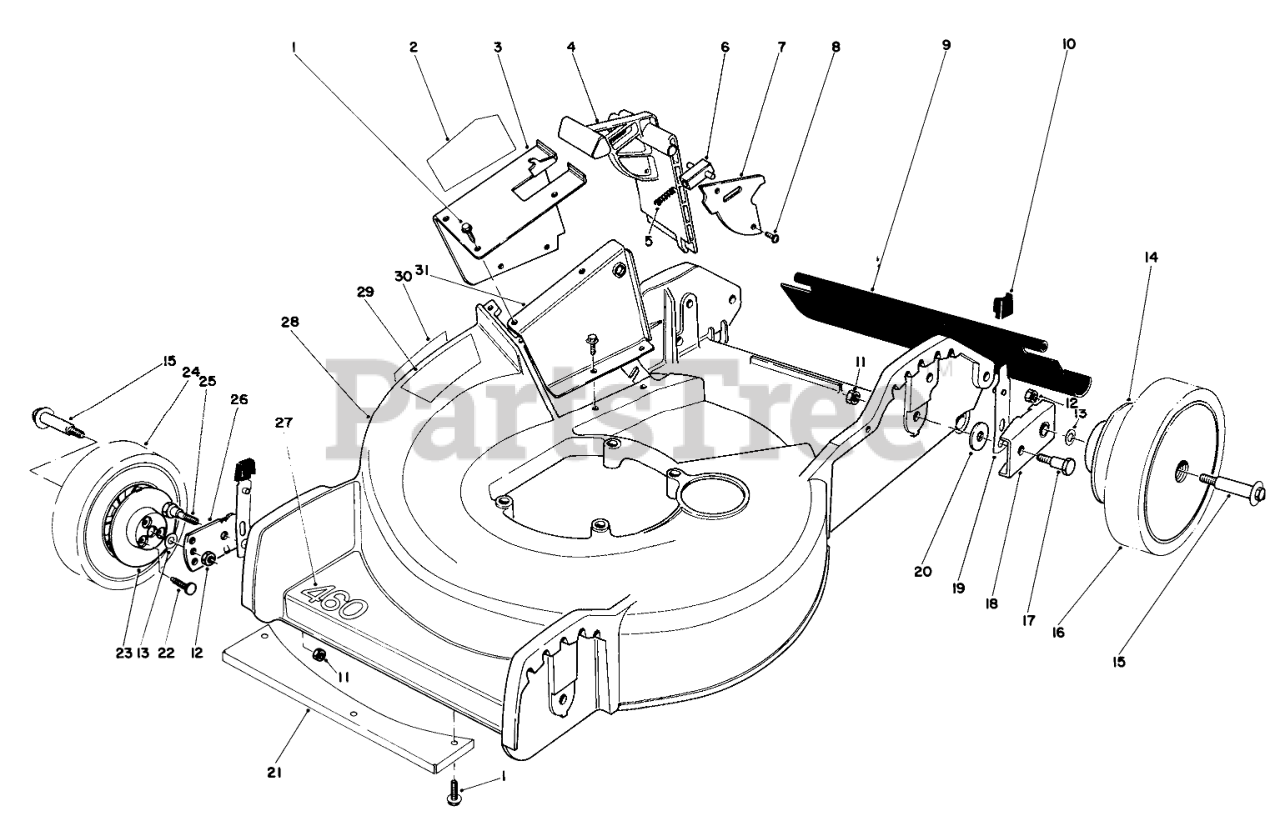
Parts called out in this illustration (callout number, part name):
1	SCREW
2	OBS DANGER DECAL FR/E/GER
3	Tunnel-Outer (Incl. Ref. #2)
4	Door Mulching
5	SPRING-COMPRESSION, LATCH
6	Door Latch
7	Cover Door
9	SHIELD - TRAILING
10	KNOB-ARM
11	NUT-LOCK, NI
12	Nut
13	WASHER
14	Wheel Cover Inner
15	BOLT-WHEEL
16	Wheel & Tire Assembly
17	PIVOT SCREW
18	HP PIVOT ARM ASM
19	SPRING ARM ASM
20	PIVOT WASHER
21	18" FRONT SHIELD
22	SCREW-DRIVE
23	Wheel Cover Inner
24	Wheel & Tire Assembly
25	PIVOT SCREW
26	PIVOT ARM ASSY
27	Decal-460
28	Housing
29	Decal-Place Foot Here
30	STEP PAD DECAL
31	Inner Tunnel
